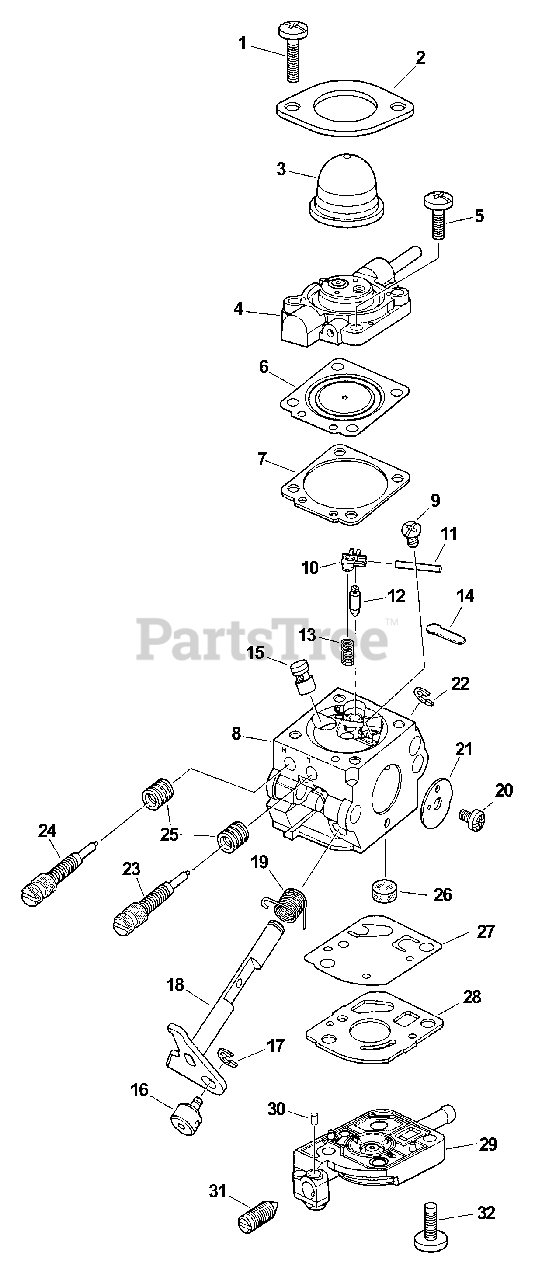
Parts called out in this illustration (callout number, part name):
1	SCREW, PURGE BASE
2	RETAINER, PURGE BULB
3	BULB, PURGE
4	BASE, PURGE
5	SCREW, RETAINER
6	DIAPHRAGM, METERING
7	GASKET, METERING
8	BODY, CARBURETOR
9	SCREW, METERING LEVER PIN
10	LEVER, METERING
11	PIN, METERING LEVER
12	VALVE, INLET NEEDLE
13	SPRING, METERING LEVER
14	PLUG, WELCH
15	NOZZLE, CHECK VALVE
17	RING, RETAINING
18	SHAFT, THROTTLE
19	SPRING, RETURN
21	VALVE, THROTTLE
22	RING, RETAINING
23	NEEDLE - LOW SPEED
24	NEEDLE - HIGH SPEED
26	STRAINER
27	DIAPHRAGM, PURGE
28	GASKET, PURGE
29	BASE, PURGE
30	PIECE, FRICTION
31	SCREW, IDLE ADJUST
32	SCREW, PUMP COVER
